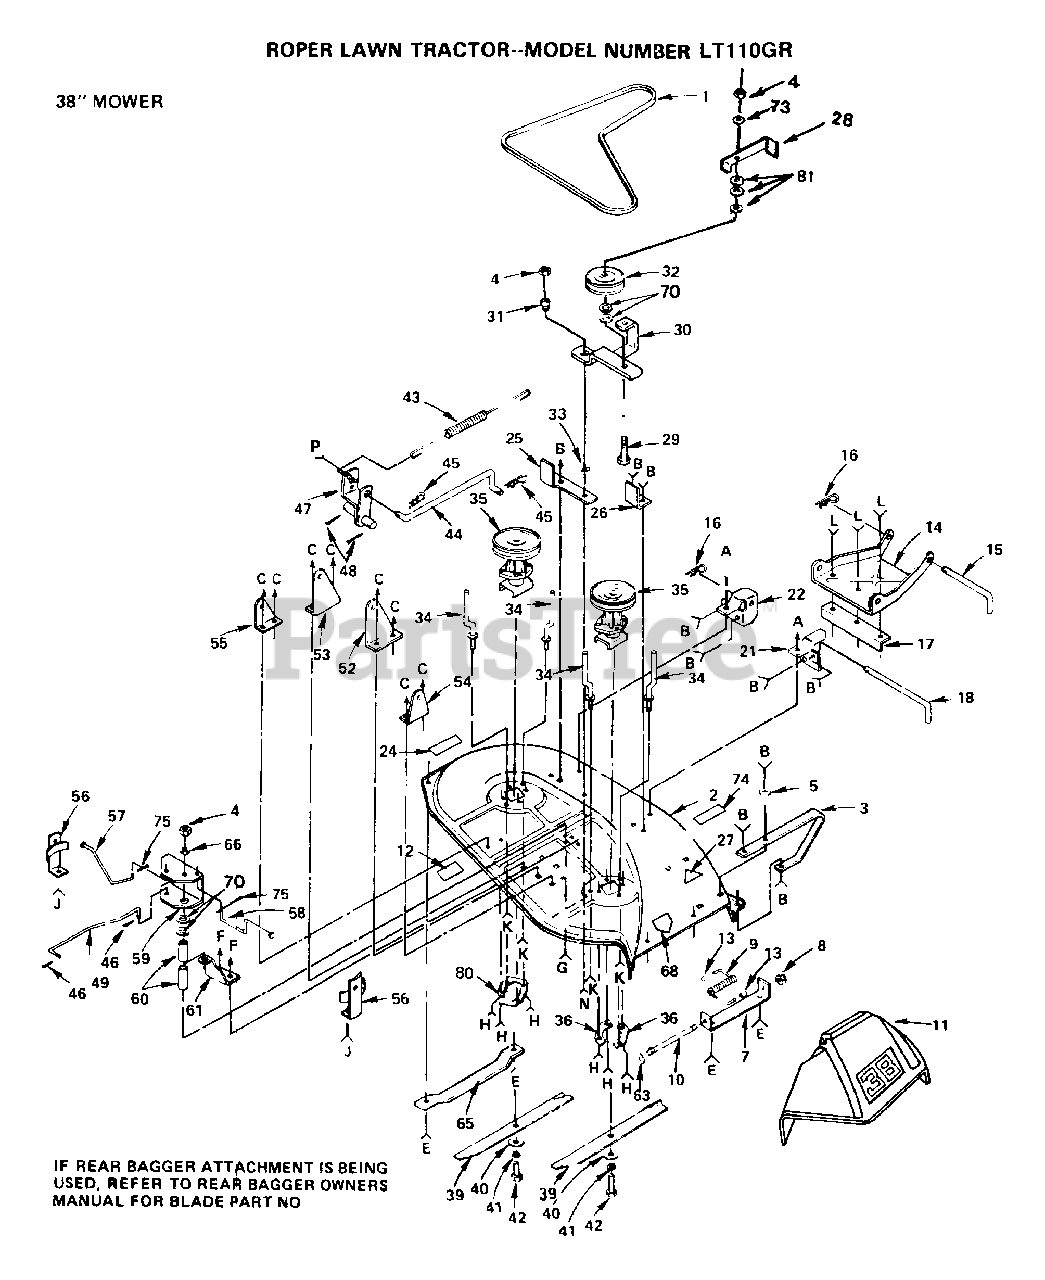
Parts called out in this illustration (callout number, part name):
1	BELT-V.79.1.MWR
5	WASHER M
8	NUT PUSH M
10	ROD-HINGE T
11	DEFLECTOR-SHLD T
12	DECAL.LT
13	CAP-SLEEVE LT
14	LINK.PARALLEL
15	"ROD, FRT. PARAL T"
16	SPRING.RETAINER
17	LINK STOP
21	BRACKET RH LT
22	BRACKET LH T
24	DECAL INSTRUCTION CAUTION
25	SUPPORT ARM T
26	STOP T
29	BOLT
31	SPACER RETAINER
32	IDLER-FLAT T
33	"WASHER, WEAR LT"
34	BELT KEEPER LT
36	SUPPORT PLATE LT
40	WASHER
42	No Desciption for Part
45	SPRING.RETAINER
47	ROCKSHAFT T
49	ROD BRAKE LT
54	"BRKT,SUSP RH T"
55	"BRKT,SUSP REAR LH"
56	BRAKE LT
57	"ROD, BRAKE LH LT"
58	ROD BRAKE LT
59	"BRK,BRAKE,PVT LT"
60	SPACER BRAKE LTV
61	BRACKET SUPT LTV
63	WASHER
65	RUNNER-LH M
66	WASHER
70	WASHER
73	WASHER
74	DECAL.WARNING.T
80	PLATE SUPPORT
